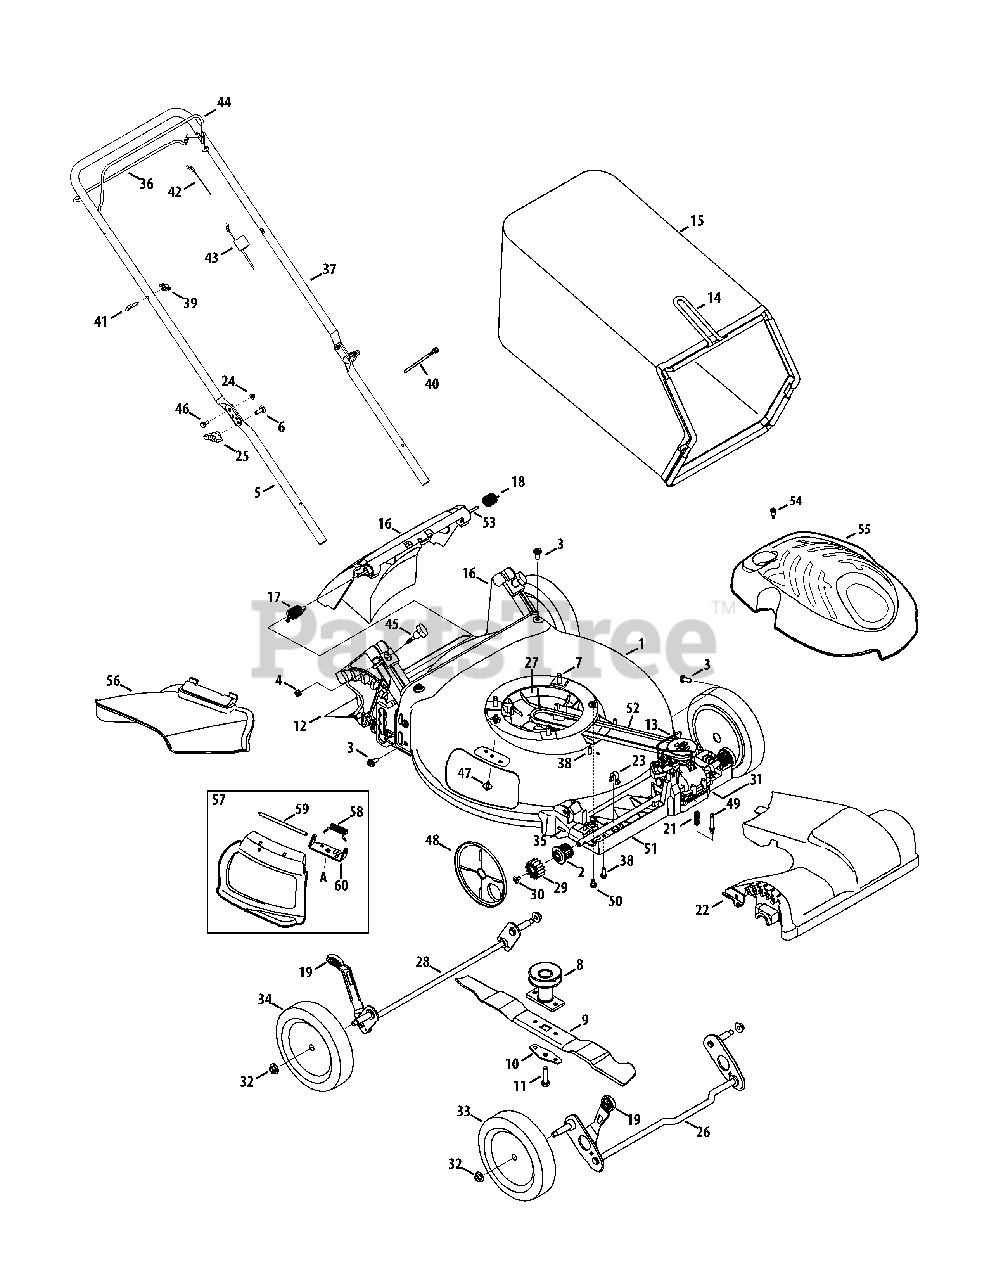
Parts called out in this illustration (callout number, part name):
1	Deck , 21"
2	Bearing Assembly
3	Screw, 5/16-14 x .750
4	Nut, Sq., 1/4-20
5	Lower Handle
6	Carriage Screw ,5/16-18
7	Screw, 3/8-16 x 1.00
8	Blade Adapter
8	Blade Adapter (Kohler)
9	Mulching Blade
10	Blade Bell Support
11	Screw, 3/8-24 x 1.50
12	Trailing Shield
13	Transmission Wire
14	Grass Catcher Frame
15	Grass Bag
16	Rear Discharge Door Assembly
17	Torsion Spring - RH
18	Torsion Spring - LH
19	Adjustment Lever Knob
20	Screw, 1/4-20 x .500
21	Compression Spring
22	Front Cover
23	Front Axle Clip
24	Nut, Flange Lock, 1/4-20
25	Wing Knob
26	Front Axle Assembly
27	Engine Baffle
28	Rear Axle Assembly
29	Spur Gear, 14T - RH
29	Spur Gear, 14T - LH
30	Screw, 1/4-20 x .390
31	Transmission Assembly
32	Flange Lock Nut, 3/8-16
33	Front Wheel
34	Rear Wheel
35	Dowel Pin
36	Drive Control
37	Upper Handle
38	Screw, 1/4-15 x .750
40	Cable Tie
41	Rope Guide
42	Control Cable
42	Control Cable (Kohler)
43	Drive Cable
44	Blade Control
45	Wing Nut
46	Sldr. Screw, .375 x .126 x 1/4-20
47	Screw, 1/4-20 x .500
48	Wheel Dust Cover
49	Spring Body
50	Scr., Shldr., 1/4-20 x .50
51	Lower Tray
53	Pivot Rod
54	Screw, #12-16 x 1.00
55	Engine Shroud
56	Side Discharge Chute
57	Mulch Plug (Incl. 58-60)
58	Torsion Spring
59	Hinge Pin
60	Chute Deflector Bracket
